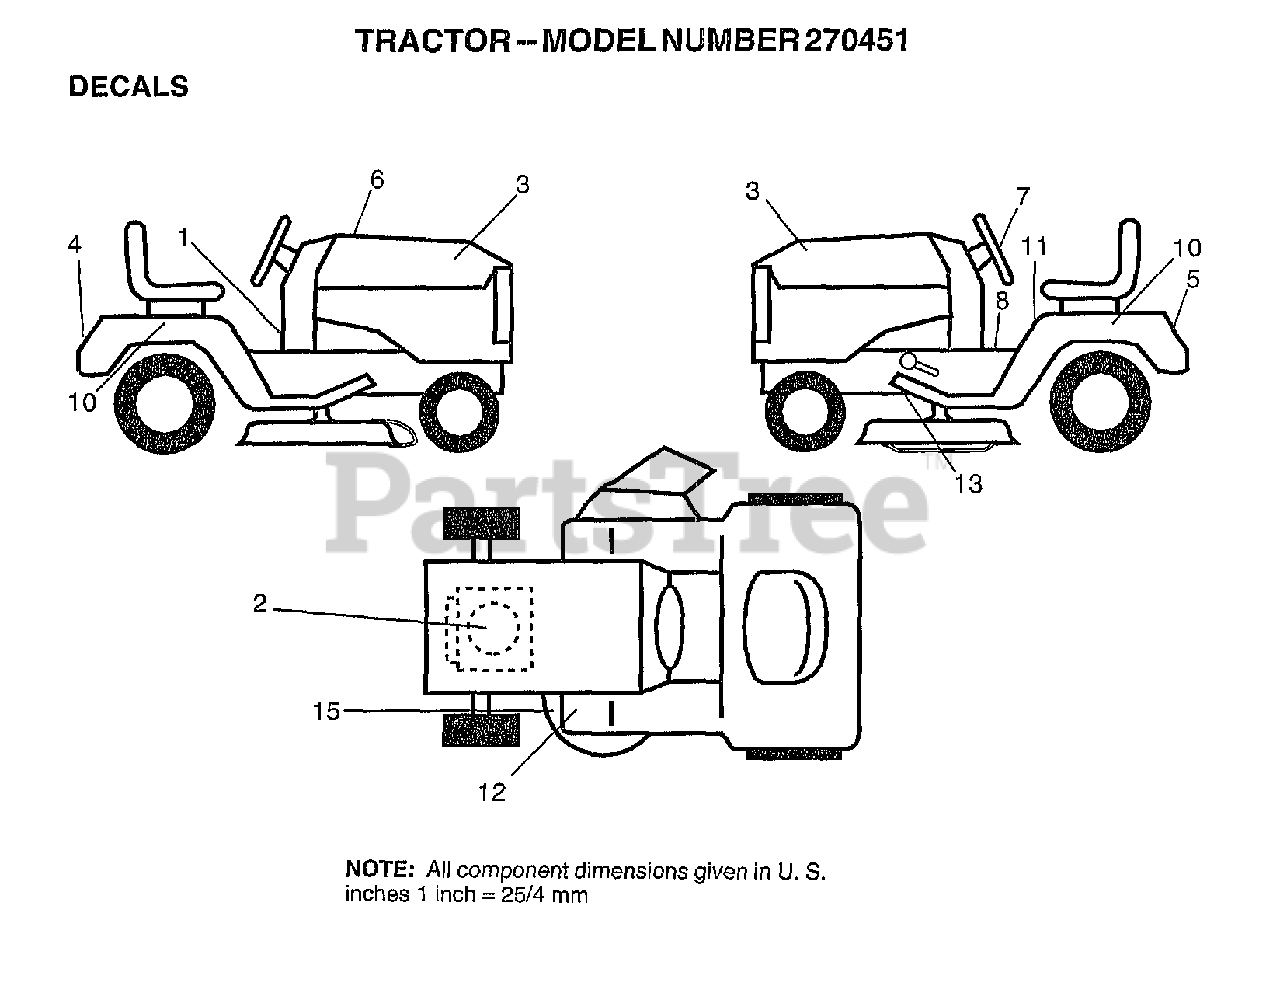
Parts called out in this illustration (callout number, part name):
1	DECAL,DASHL
2	DECAL, ENGINE
3	DECAL, HOOD
4	DECAL, FENDER
5	DECAL.BATRY.3-3908
6	DECAL, REPLACEMENT PARTS
7	DECAL, STEERING
8	"DECAL DASH,OPER."
10	DECAL, FENDER
11	"DECAL-FENDER,DANG"
13	DECAL.BELT-V.SCHM
15	DECAL
